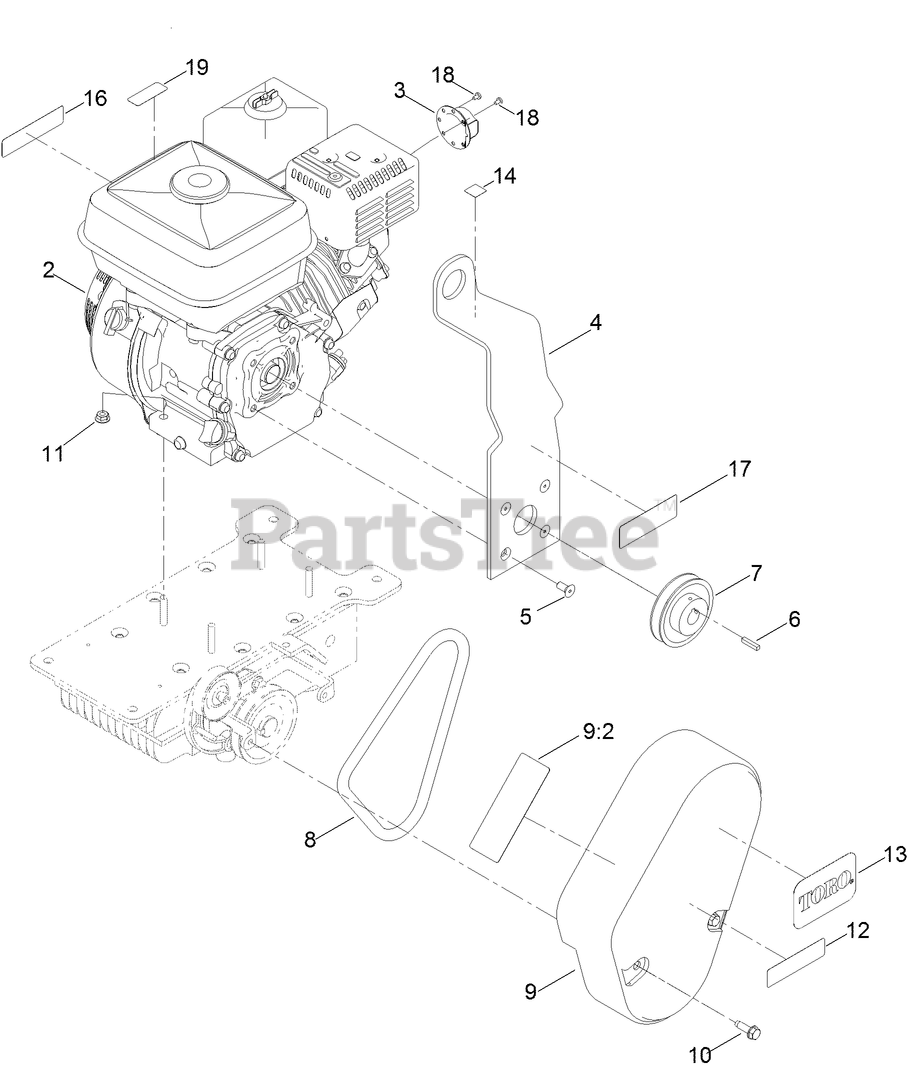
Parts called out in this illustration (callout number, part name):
3	DEFLECTOR
4	PLATE-EYE, LIFT
5	SCREW
6	KEY-SQUARE
7	SHEAVE
8	BELT-V
9	BELT GUARD ASM
9:2	DECAL-WARNING
10	SCREW-THD ROLL, HWH
11	NUT-FLANGE
14	DECAL-POINT, LIFT
16	DECAL-ARRESTOR, SPARK
17	DECAL-WARNING
18	SCREW-SELF TAPPING
19	DECAL-WARNING, ETHANOL
